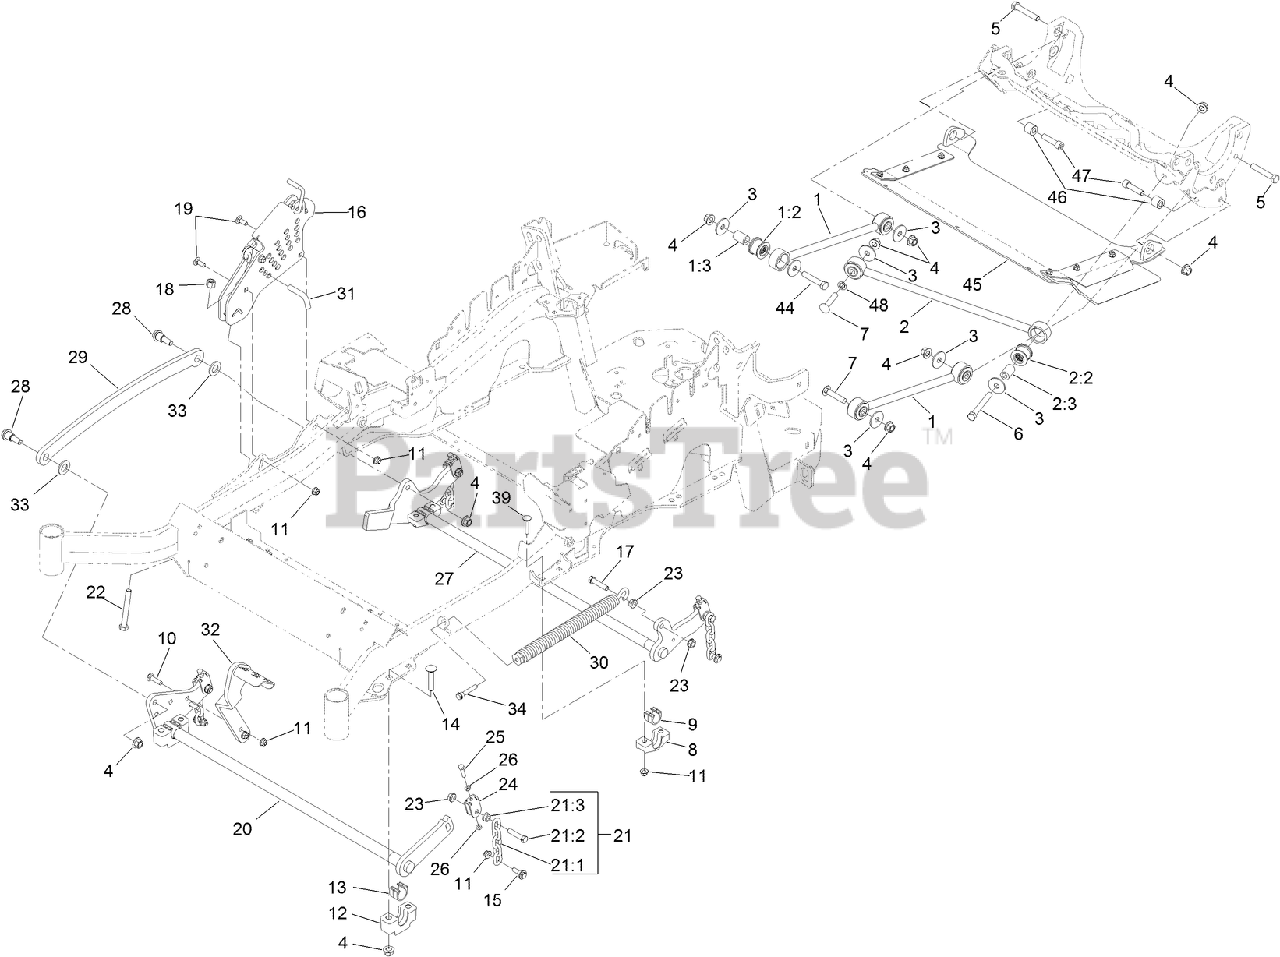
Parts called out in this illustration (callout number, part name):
1	DECK STRUT ASM
1:2	BUSHING-SUSPENSION, RUBBER
1:3	SPACER
2	PANHARD ROD ASM
2:2	BUSHING-SUSPENSION, RUBBER
2:3	SPACER
3	WASHER-THRUST
4	NUT-LOCK
5	SCREW-HH
6	SCREW-HH
7	SCREW-CARR
8	SUPPORT-CROSS SHAFT, REAR BEARING
9	BEARING-CROSS SHAFT, REAR
10	SCREW-CARR
11	NUT-HF, NI
12	SUPPORT-CROSS SHAFT, BEARING
13	BEARING-CROSS SHAFT, FRONT
14	BOLT-CARR
15	SCREW-SHOULDER, HHF
16	HOC ASM
17	SCREW-HH
18	NUT-LOCK, NI
19	BOLT-CARR
20	DECKLIFT-FRONT
21	DECK LIFT CHAIN ASM
21:1	CHAIN-LIFT, DECK
21:2	SCREW-HH
21:3	NUT-HF
22	BOLT-TAP
23	NUT-HF
24	YOKE-ADJUST, DECK
25	SCREW-HH
26	NUT-JAM
27	LIFT-DECK, REAR
28	SCREW-SHOULDER, HHF
29	LINK-LIFT, DECK
30	SPRING-EXTENSION
31	PIN-HOC
32	LEVER-FOOT
33	WASHER-FLAT
34	BOLT-SHOULDER
39	SCREW-CARR
44	SCREW-HH
45	DISCHARGE TUNNEL ASM
46	BUSHING-SLEEVE
47	SCREW-HH
48	NUT-PUSH
